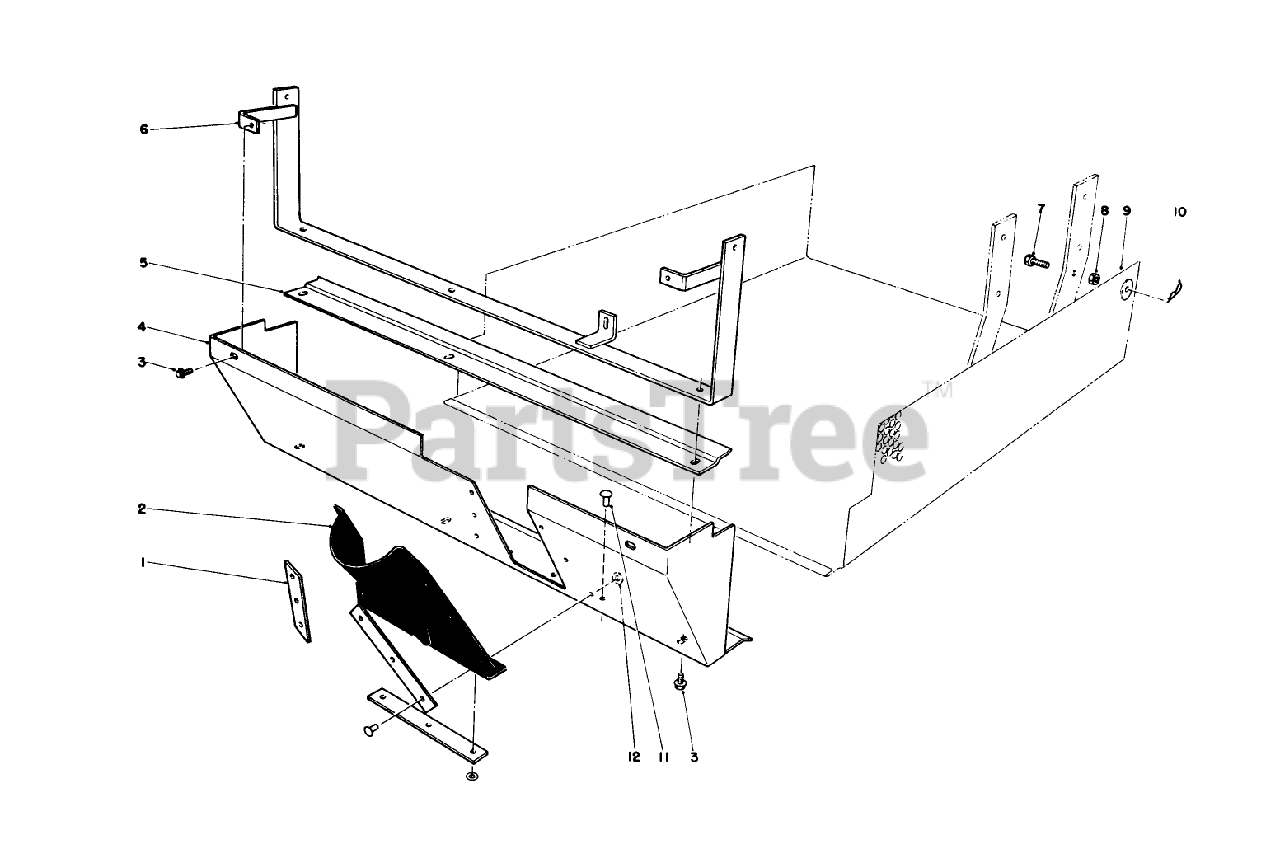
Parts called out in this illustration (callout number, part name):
2	RUBBER SHIELD
3	SCREW
6	DEFLECTOR MT WA *R
8	NUT-LOCK, NI
10	PIN-COTTER, HAIR
11	RIVET-POP
12	WASHER-FLAT
